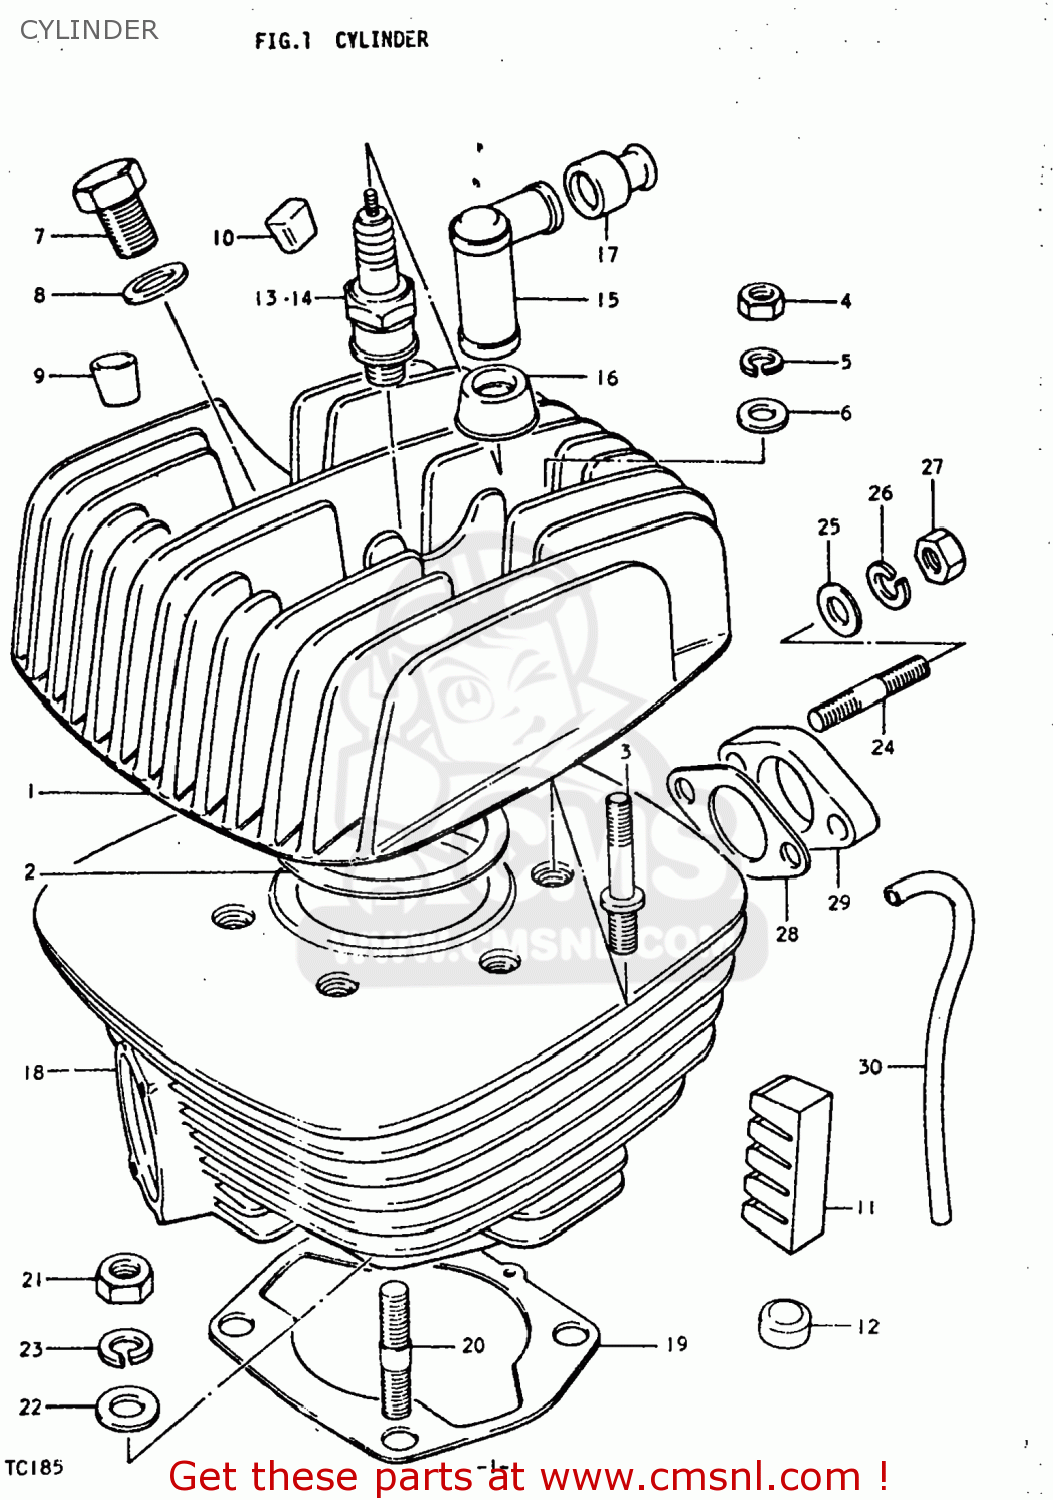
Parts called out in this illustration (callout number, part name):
1	HEAD,CYLINDER
2	GASKET,CYLINDER HEAD (NAS)
3	BOLT,STUD
4	NUT (8MM)
5	LOCK WASHER
6	WASHER
7	PLUG
8	GASKET(14X19.2X2) (NAS)
9	PAD,CYLINDER HEAD
10	PAD,CYLINDER
11	PAD,CYLINDER
12	PAD,CYLINDER
13	PLUG,SPARK(B7HS)
14	SPARK PLUG W22FS
15	CAP,SPARK PLUG
16	SEAL,SPARK PLUG
17	SEAL,SPARK PLU
18	CYLINDER
19	GASKET,CYLINDER (MCA)
20	STUD 10X30
21	NUT
22	WASHER
23	LOCK WASHER
24	STUD BOLT
25	WASHER
26	LOCK WASHER
27	NUT
28	GASKET,CARBURETOR (MCA)
29	GASKET,CARBURETOR INSULATOR (NAS)
30	HOSE
